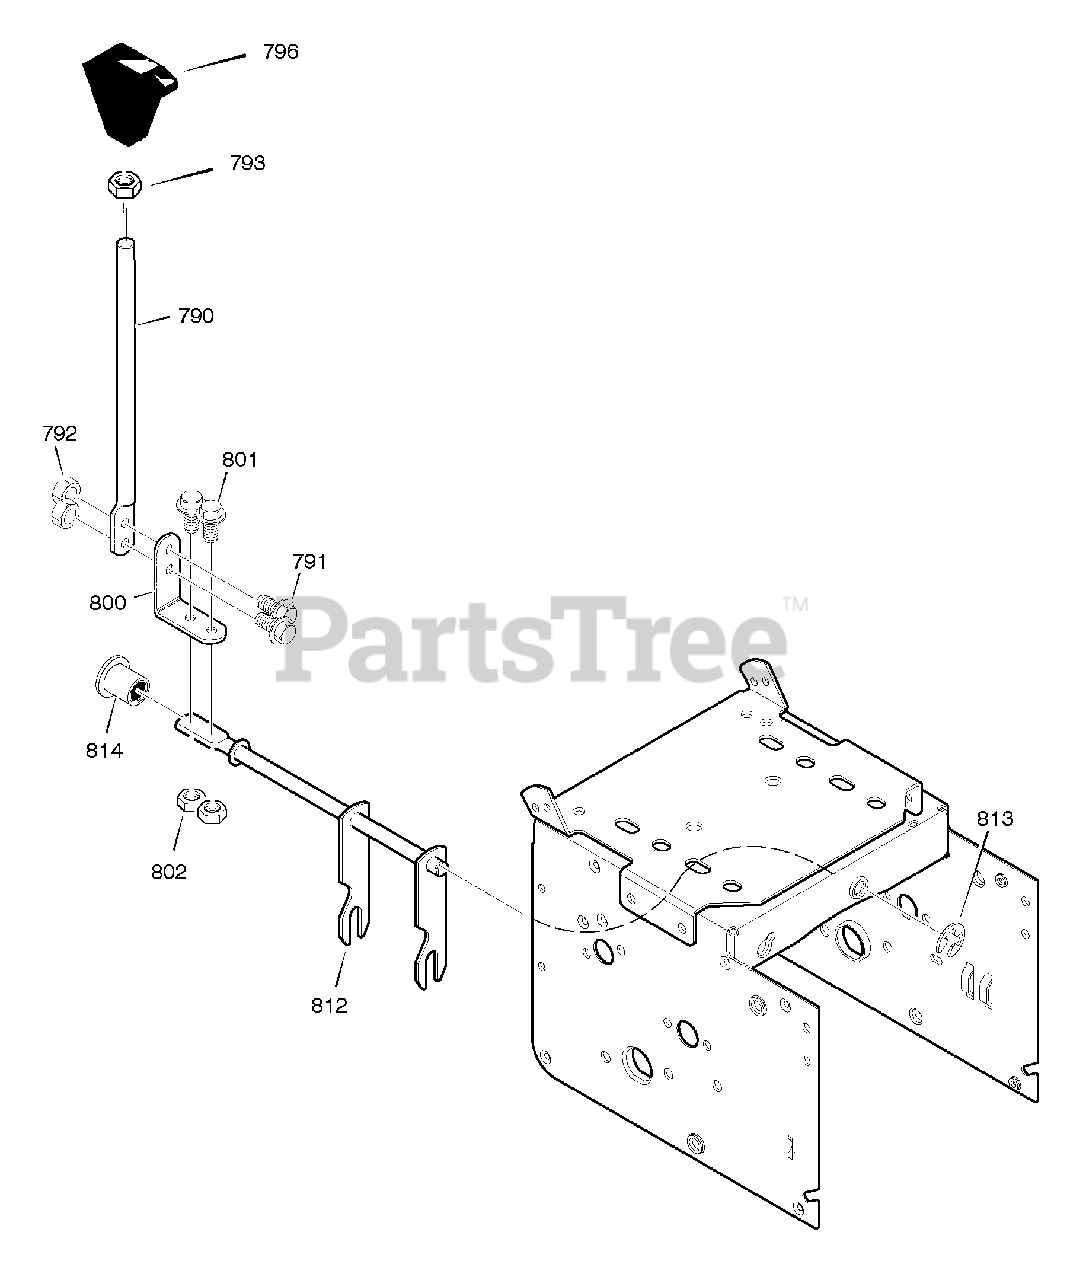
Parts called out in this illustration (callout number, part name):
790	ROD, SHIFT
791	SCREW, 1/4-20X.75
792	NUT, 1/4-20
793	NUT, JAM
796	KNOB, SLIP
800	LEVER, SPRING
801	SCREW, 1/4-20X.75
802	NUT, 1/4-20
811	BEARING, FLANGED
812	ROD ASSY., SPEED SELECT
813	RETAINER, RING
